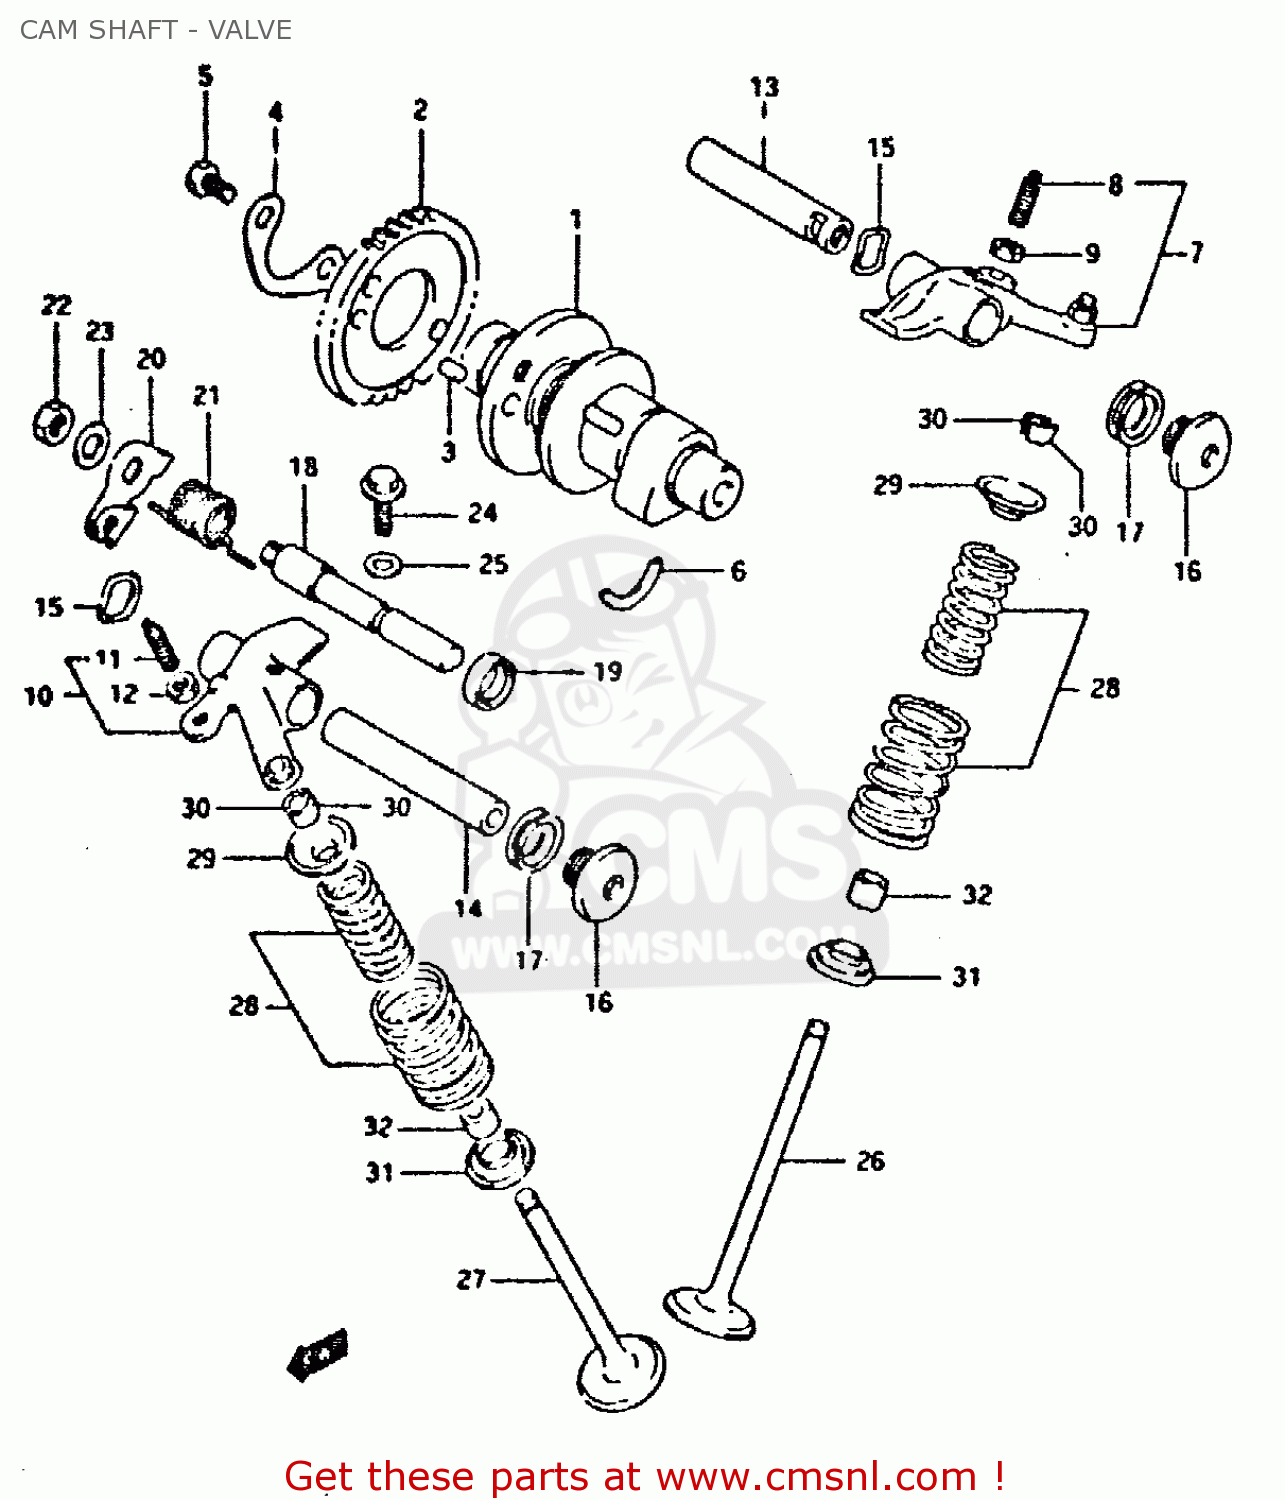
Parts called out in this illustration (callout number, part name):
1	SHAFT COMP,CAM
2	SPROCKET,CAMSHAFT
3	PIN(5X8)
4	WASHER,SPROCKET
5	BOLT(6X10.5)
6	C RING
7	ARM,VALVE ROCKER,INTAKE
8	SCREW,TAPPET ADJUSTING
9	NUT,TAPPET ADJUSTING
10	ARM,VALVE ROCKER EXHAUST
11	SCREW,TAPPET ADJUSTING
12	NUT,TAPPET ADJUSTING
13	SHAFT,VALVE ROCKER ARM INTAKE
14	SHAFT,VALVE ROCKER ARM EXHAUST
15	WASHER
16	PLUG,14X12
17	GASKET(13.8X18.8X4.8) (NAS)
18	SHAFT,DECOMP
19	SEAL,OIL(10X17X6)
20	LEVER,DECOMPRESSION SHAFT
21	SPRING
22	NUT
23	WASHER
24	BOLT
25	GASKET(6.4X11.5X0.8) (NAS)
26	VALVE,INTAKE
27	VALVE,EXHAUST
28	SPRING SET,VALVE
29	RETAINER,VALVE SPRING
30	COTTER VALVE
31	SEAT,VALVE SPRING
32	SEAL,OIL(5X10X9.7)
